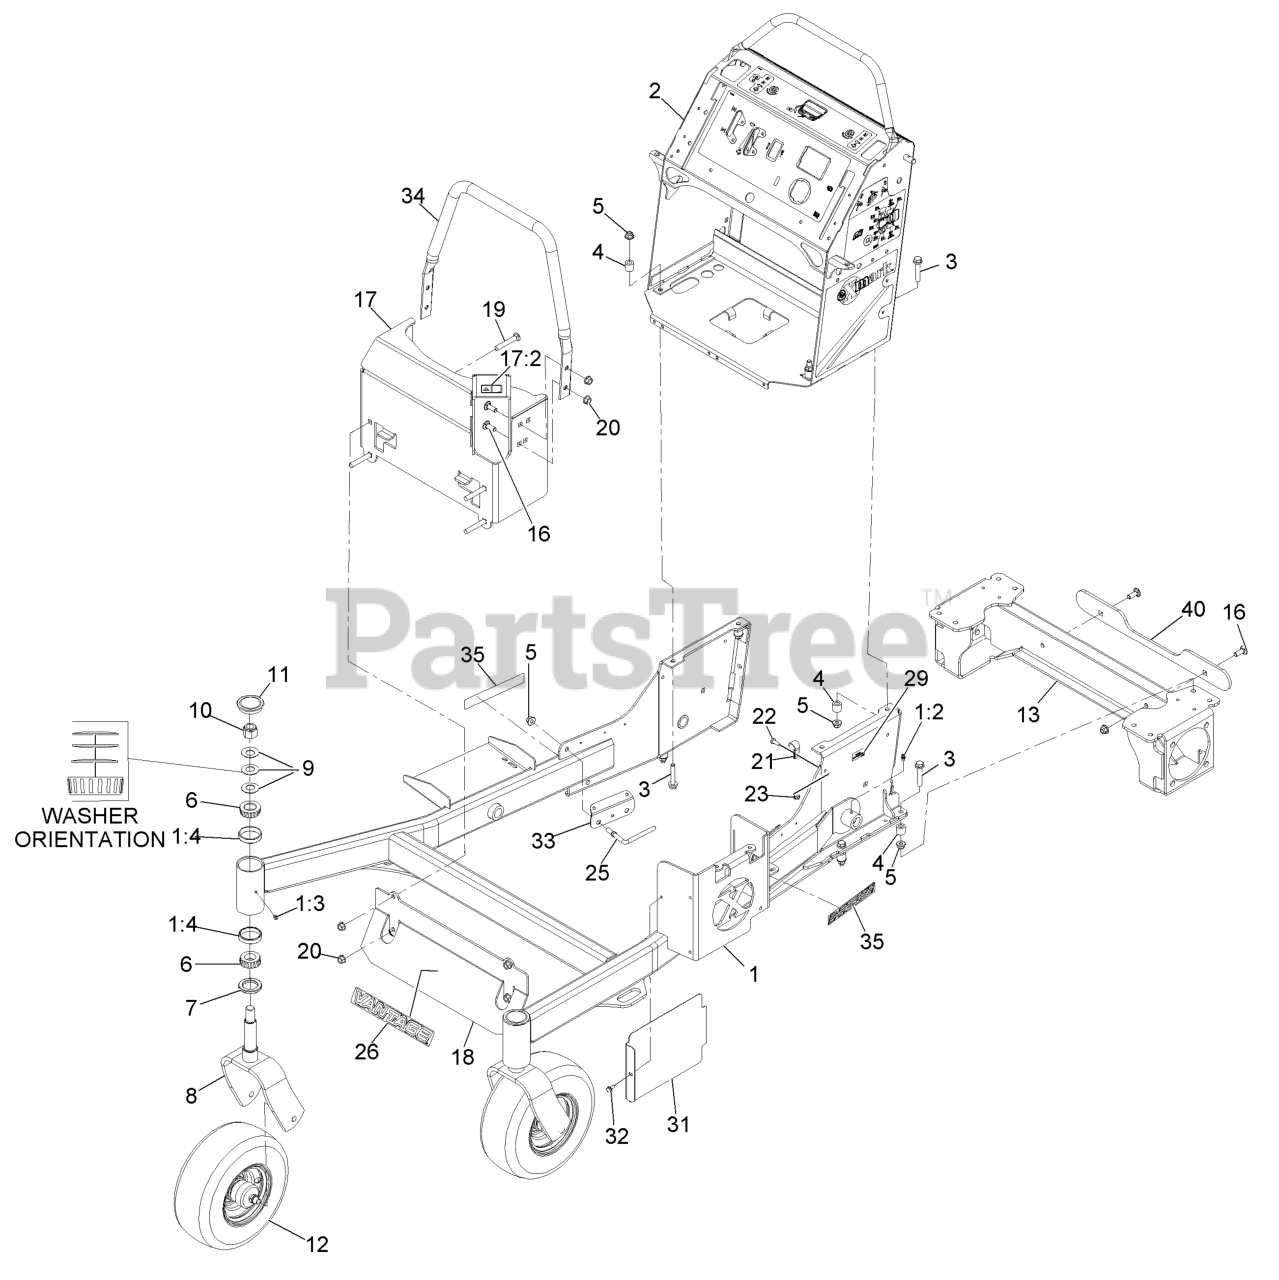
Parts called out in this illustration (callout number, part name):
1	FRONT FRAME ASM
1:2	FITTING-GREASE
1:4	CUP-BEARING
2	CONTROL TOWER ASM-EFI
3	SCREW-HHF
5	NUT-HF, NI
6	Cone-Bearing Tapered Roller
7	SEAL-GREASE
8	FORK-CASTER
9	WASHER-BELLVILLE
10	NUT-LOCK, NI
11	CAP-GREASE
12	WHEEL/TIRE AND BEARING AS
13	WELD, MOTOR FRAME
16	SCREW-CARR
17	ASM, MUFFLER GUARD W/ DEC
17:2	DECAL-WARNING
18	PANEL-GUARD
19	SCREW-CARR
21	CLAMP-CABLE
22	SCREW-HH
25	GUIDE-HOSE, SUPPORT
26	DECAL-VANTAGE LOGO
29	Decal-Patent Ttco.Com
31	SHIELD-HEAT, TALL
32	SCREW-HWH
33	GUARD-HOSE
34	TUBE-GUARD
35	DECAL-S-SERIES
40	PLATE, BUMPER SPACER
